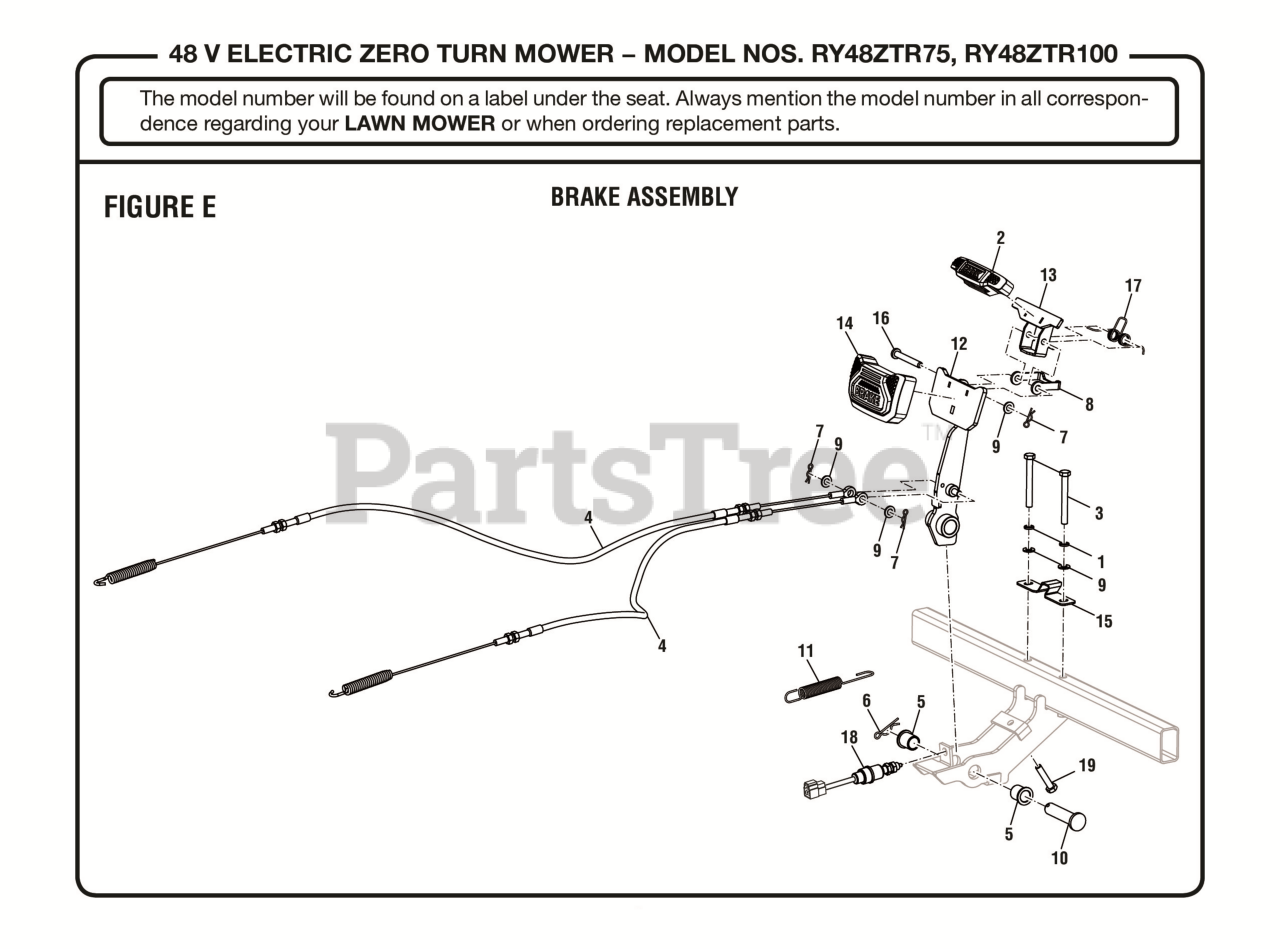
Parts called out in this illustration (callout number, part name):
1	Lock Washer (OD9.8 x ID8.5 x 5t)
2	Parking Brake Rubber Pad
3	Bolt (M8 x 70 mm, Hex Hd.)
4	Brake Cable
6	Lock Pin (16 mm)
7	Cotter Pin (8 mm)
8	Parking Brake Latch
9	Washer (OD16 x ID8.4 x 1.6t)
10	Clevis Pin
11	Brake Pedal Spring
12	Brake Pedal Lever
13	Parking Brake Pedal
14	Brake Pedal Rubber Pad
15	Brake Latch Hook
16	Clevis Pin (M8 x 60 mm)
17	Parking Brake Torsion Spring
18	Brake Switch Assembly
19	Bolt (M8 x 40 mm, Hex Hd.)
